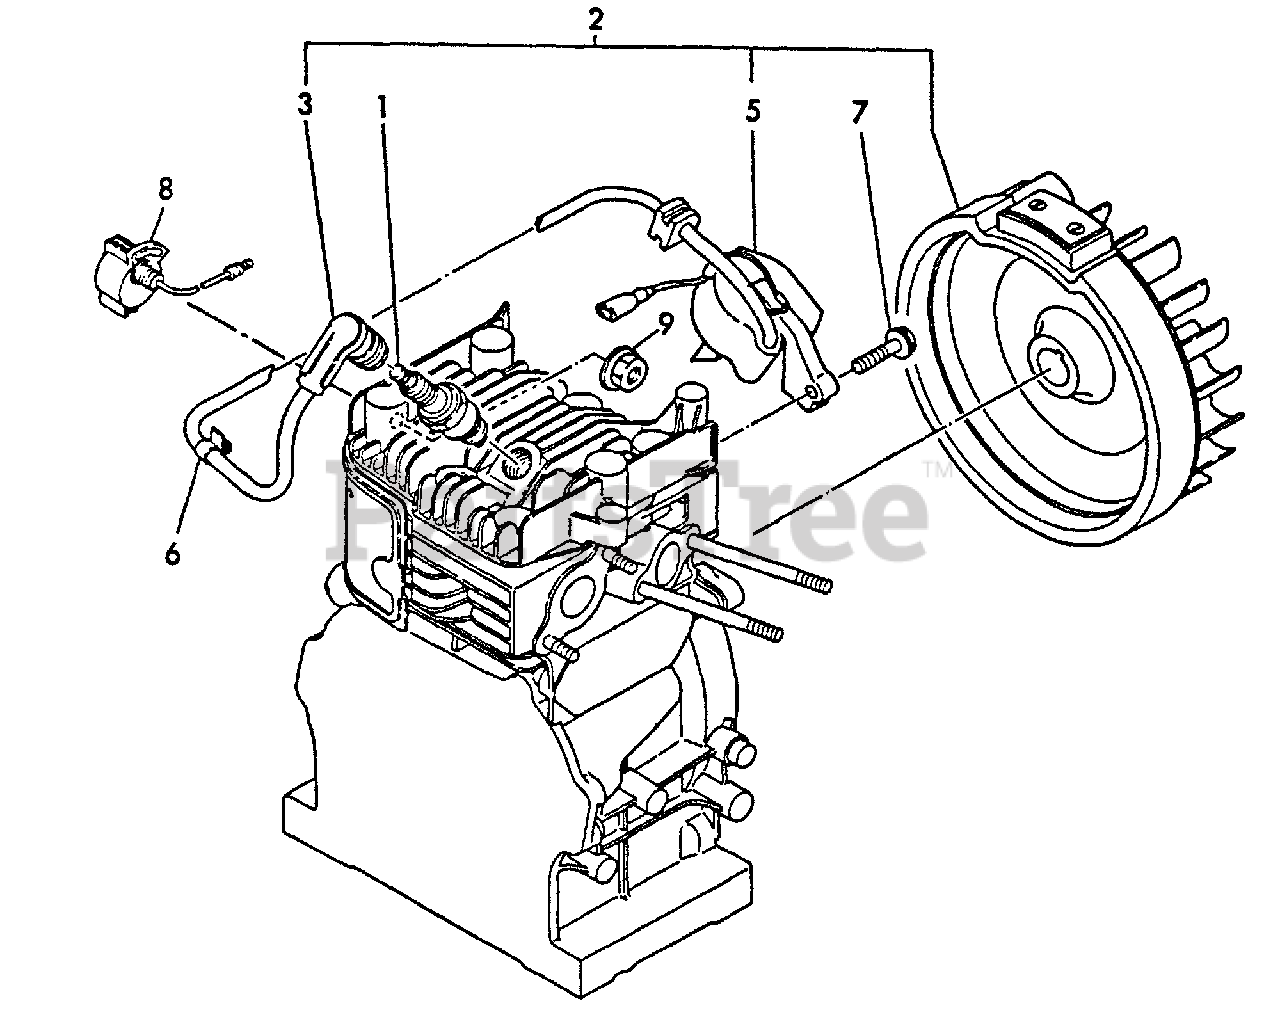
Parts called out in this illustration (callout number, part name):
1	SPARK PLUG
2	FLYWHEEL
3	CAP, PLUG
5	COIL, IGNITION
6	CLAMP
7	BOLT - 6X25
8	IGNITION SWITCH ASSY
9	NUT - 8
